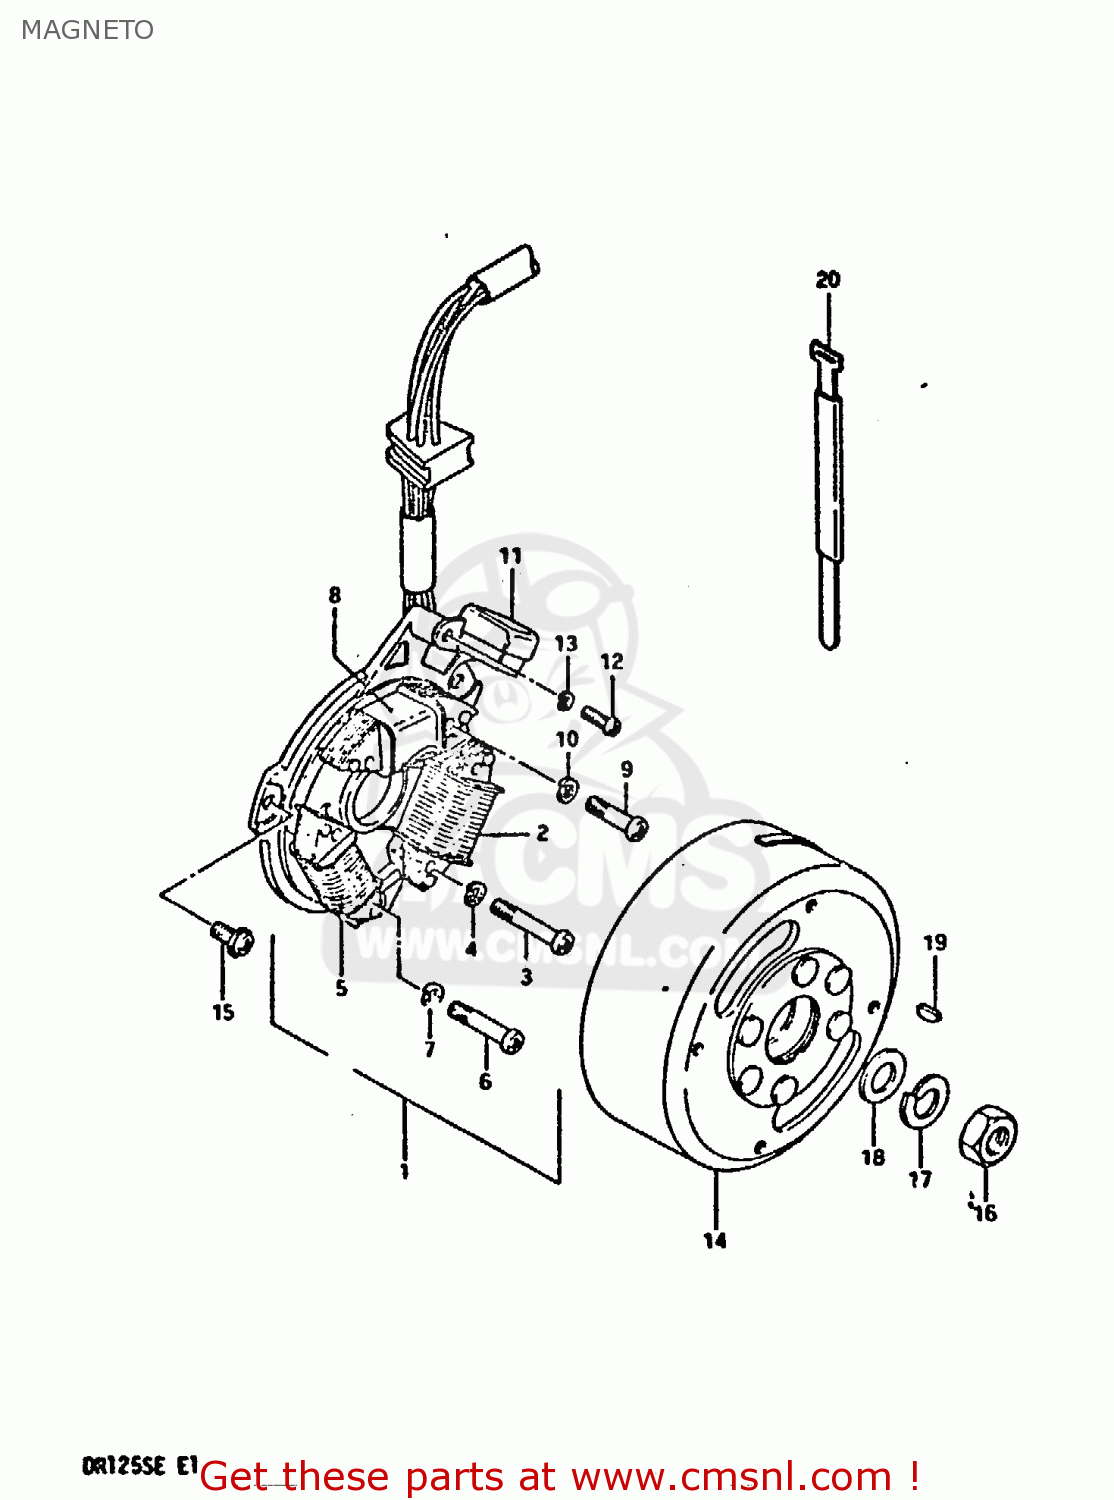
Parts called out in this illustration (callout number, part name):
1	STATOR ASSEMBLY
2	COIL,LIGHTING
3	SCREW
4	LOCK WASHER
5	COIL,CHARGING
6	SCREW
7	LOCK WASHER
8	COIL,IGNITION PRIMARY
9	SCREW
10	LOCK WASHER
11	COIL
12	SCREW
13	LOCK WASHER
14	ROTOR,FLYWHEEL
15	SCREW(5X14)
16	NUT (10MM)
17	LOCK WASHER
18	WASHER
19	KEY
20	CLAMP L:110
